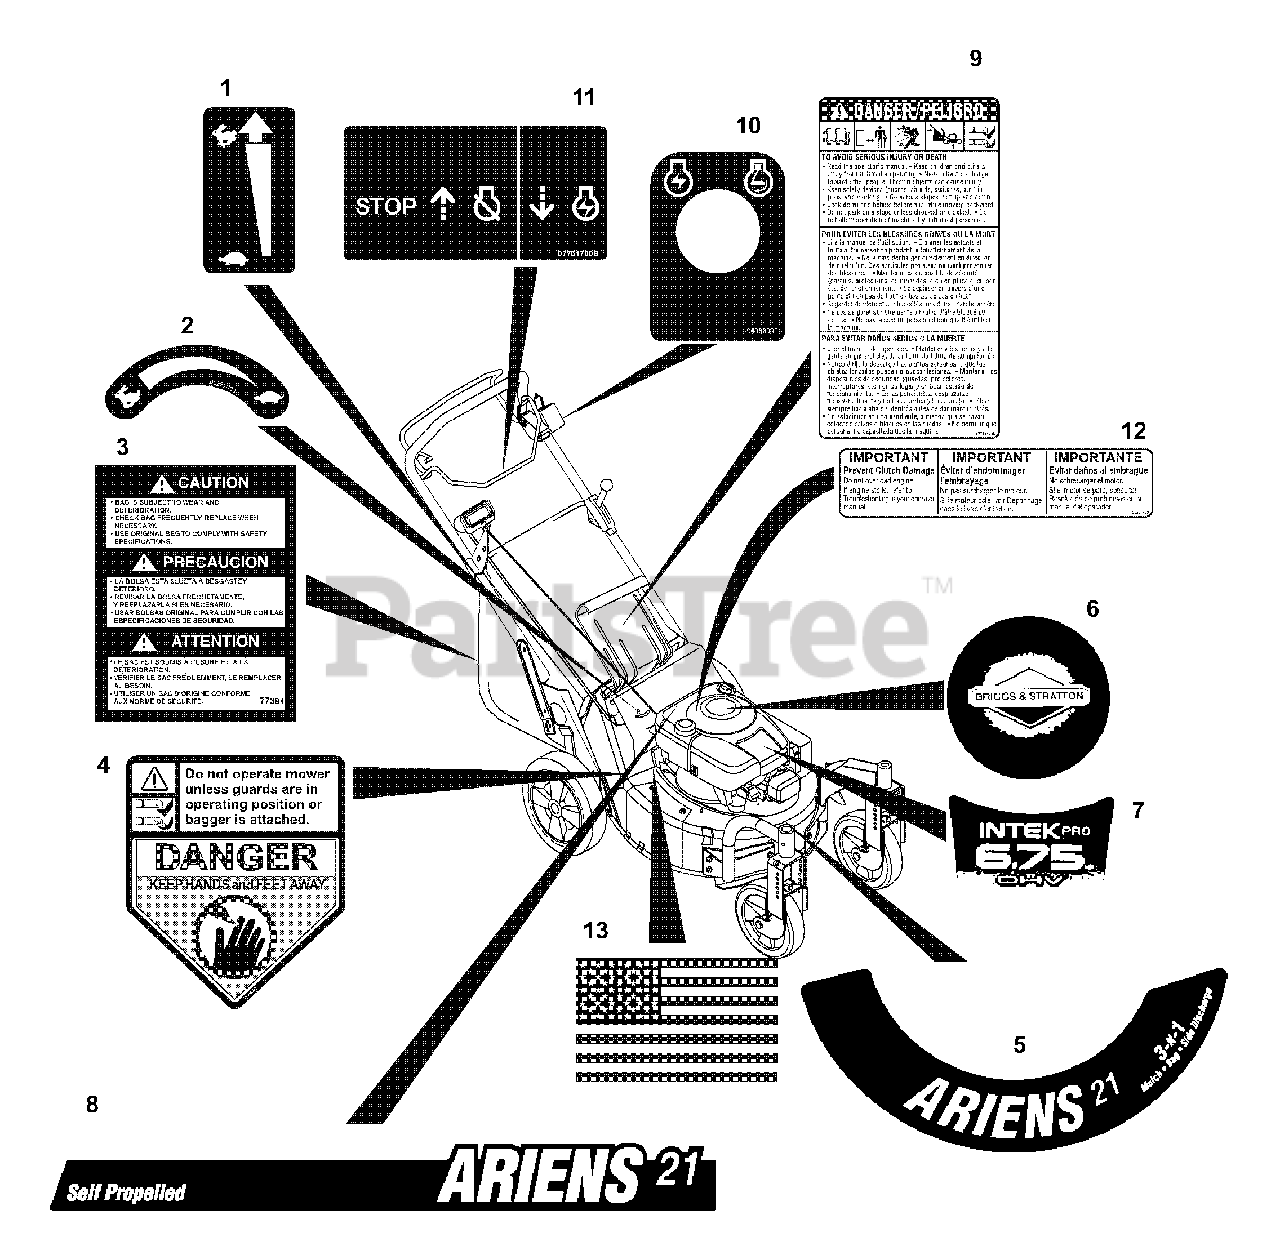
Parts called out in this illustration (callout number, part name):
1	DECAL-SPEED CONTROL
2	DECAL, TURTLE & RABBIT
3	LABEL - BAGGER 21"
4	DECAL, CPSC DANGER
5	DECAL, ARIENS DECK
6	DECAL,BRIGGS & STRATTON RECOIL
7	DECAL, BRIGGS INTEK PRO 6.75
8	DECAL, DRIVE COVER SP
9	DECAL, BILINGUAL DANGER
10	DECAL, KEYSWITCH LM 2-POS
11	DECAL - ENGINE CONTROL
12	DECAL, BBC INSTRUCTION
13	DECAL, AMERICAN FLAG
